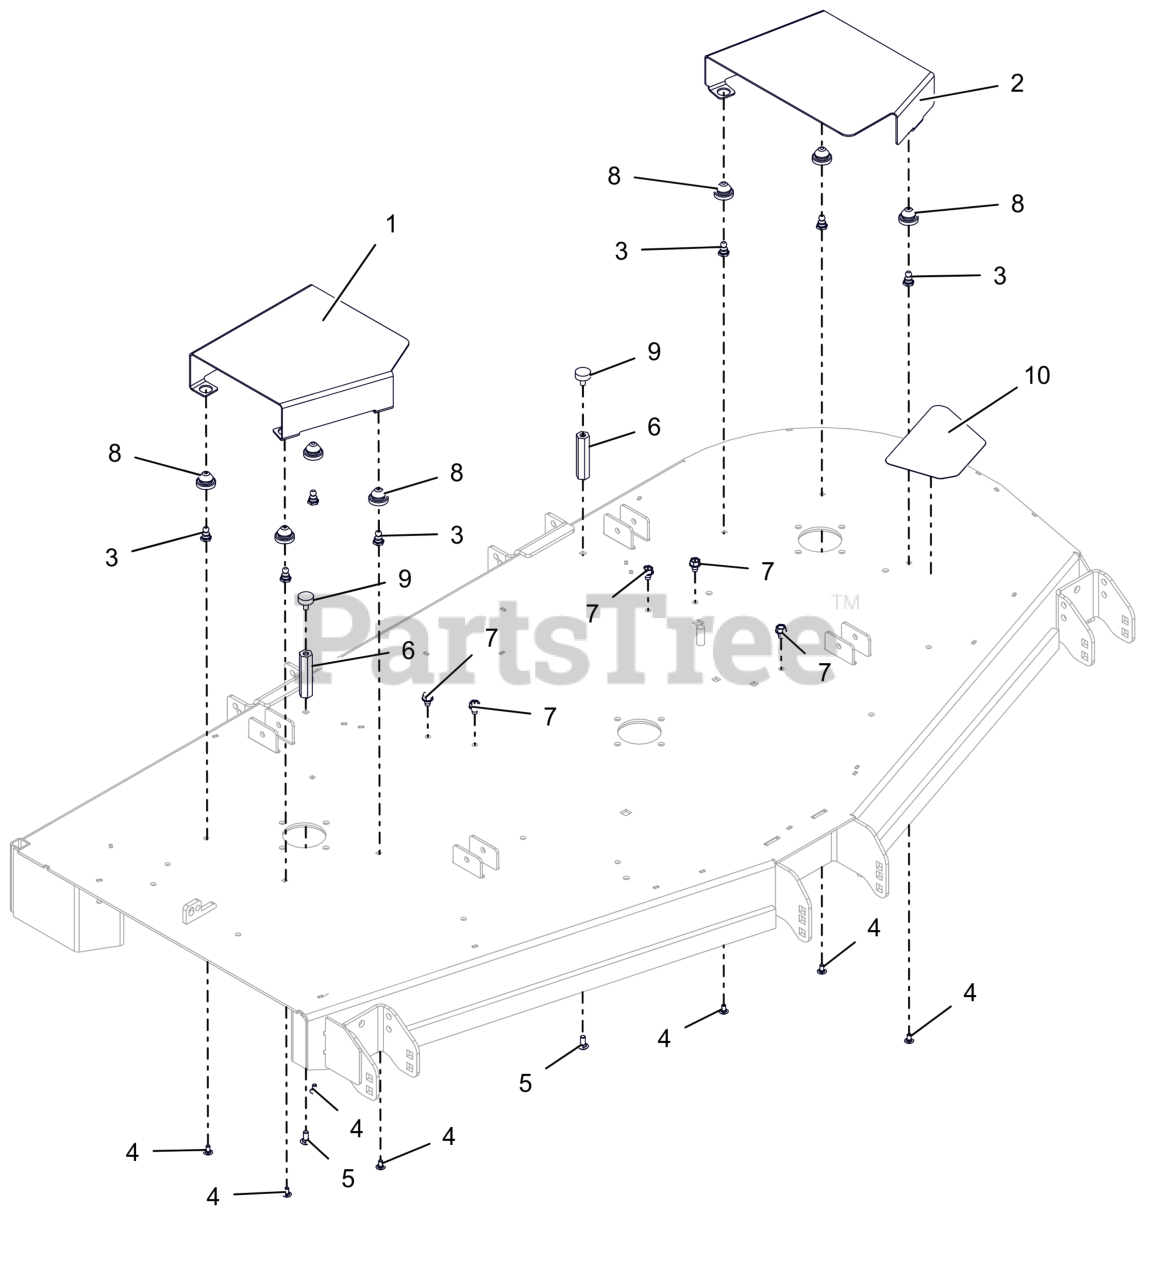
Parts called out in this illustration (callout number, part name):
1	GUARD, 72" DECK RH SPINDLE PULLEY
2	GUARD, 72" DECK LH SPINDLE PULLEY (RED)
3	STUD, BALL FEMALE .250-20 THREAD
4	BLT, RHSSN.25-20X.500 G5 ZCC
5	BTL,RHSN .313-18 X 0.75 G5 ZCC LT
6	NUT, COUPLING .312-18 X 3.250
7	SCR,TAP .375-16X.50 HWH TR ZCC
8	COUPLING, RUBBER PUSH-IN
9	BUMPER, RUBBER
10	GRIP, STEP ANTI SKID
